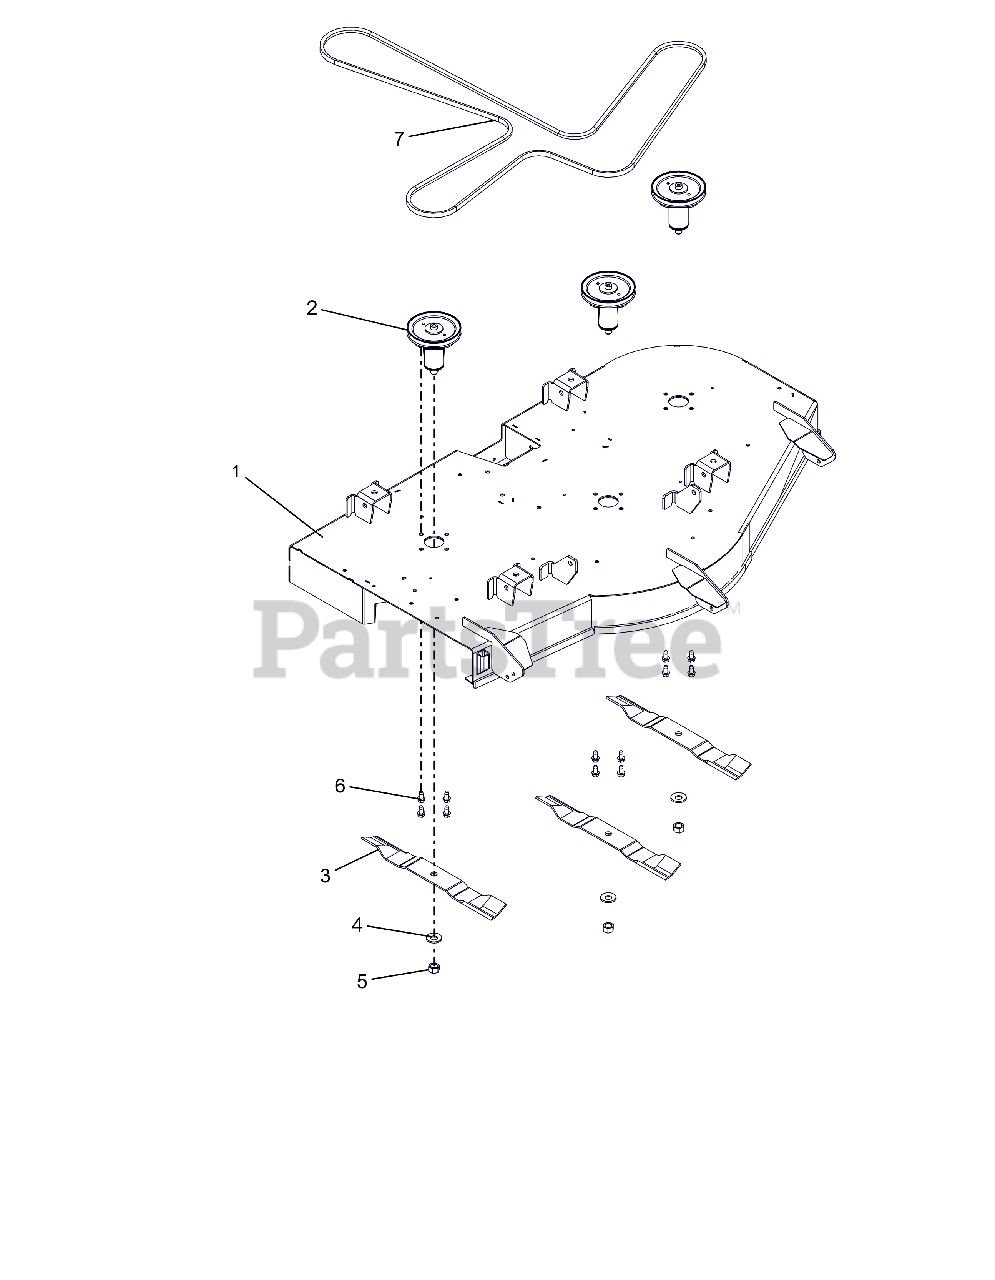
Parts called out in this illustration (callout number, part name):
1	KIT, 52" ARIENS DECK W/DECALS
2	KIT, DECK SPINDLE ASM-52
3	BLADE, 18" - 30 DEG .5 OFFSET
4	WSHR-BLVL .669X1.535X.138
5	NUT-HEX .62-18 YWZC
6	@SCR-TAP .38-16X.75 HWH TR YWZ
7	V-BELT, HA-WRAPPED
